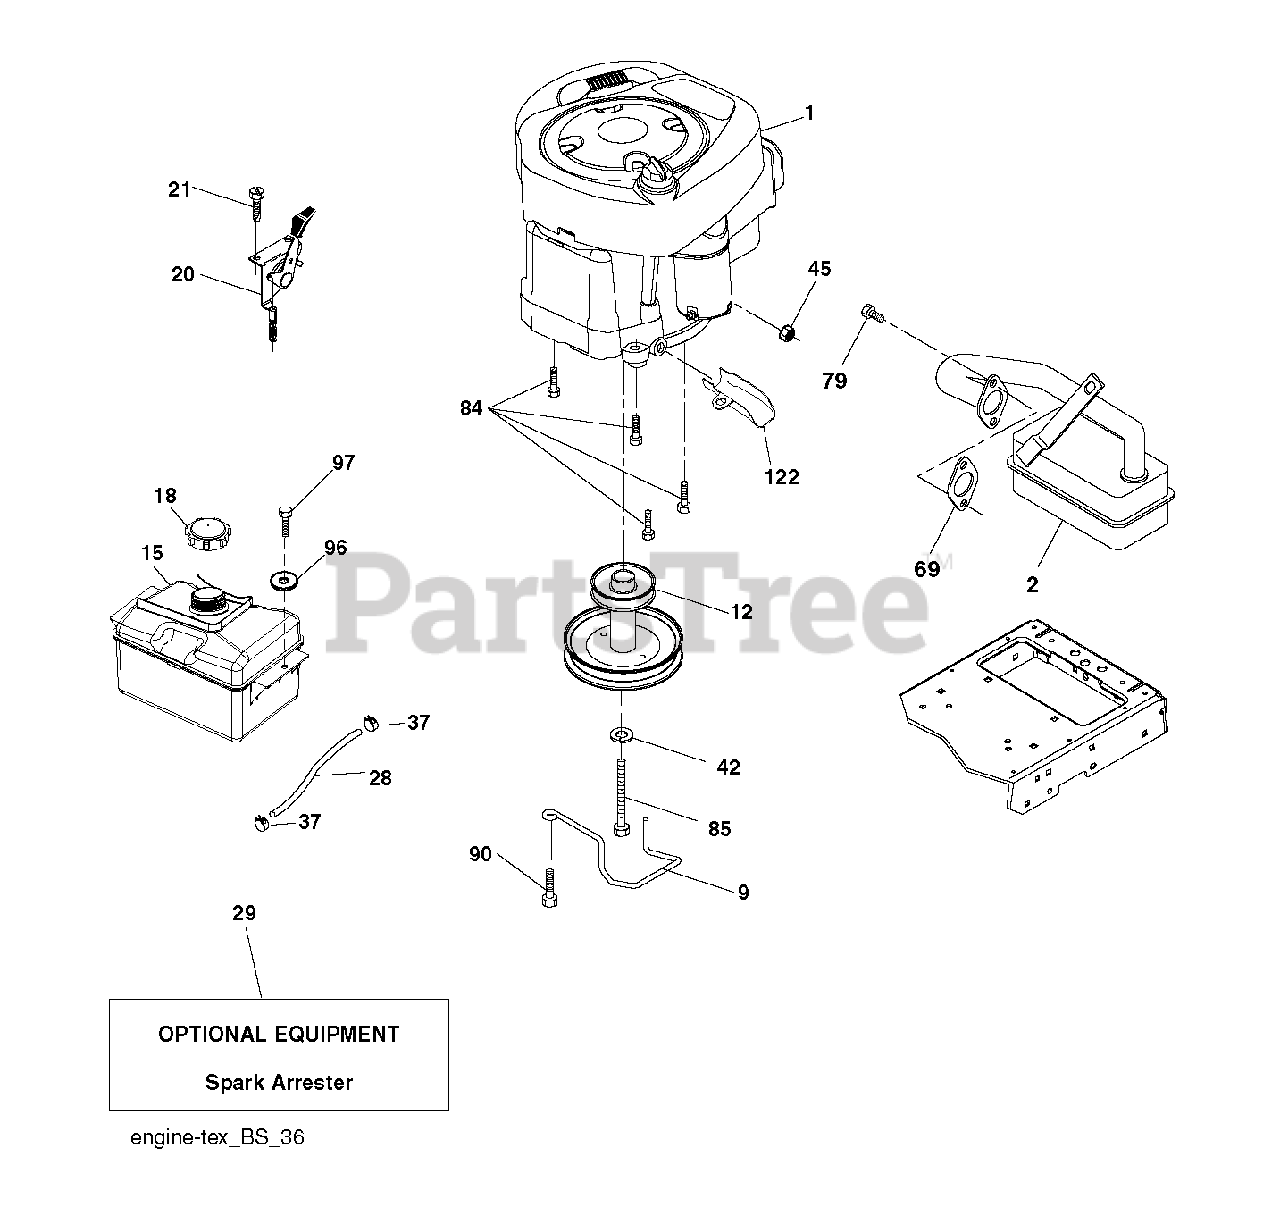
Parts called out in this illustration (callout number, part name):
9	KEEPER.BELT.ENGINE.3.25
12	PULLEY ENGINE
15	TANK FUEL FRT 1.5 GAL
18	CAP ASM.FUEL.2.25"FR.
20	CONTROL.TH/CK.C.
21	SCREW.#10 X 0.750.BOS THREAD
28	LINE.FUEL.20
29	ARRESTER SPARK (OPTIONAL)
37	HOSE CLAMP
42	LOCKWASHER
45	NUT
69	REPL BY 532 27 22-93
79	SCREW.SOCKET HD.5/16-1
84	SCREW.3/8-16
85	BOLT HEX 7/16-20X4-1/4"
90	SCREW 3/8-16X1
97	SCREW HEXWSHR 1/4-20X3/4
122	EXTENSION DRAIN OIL
